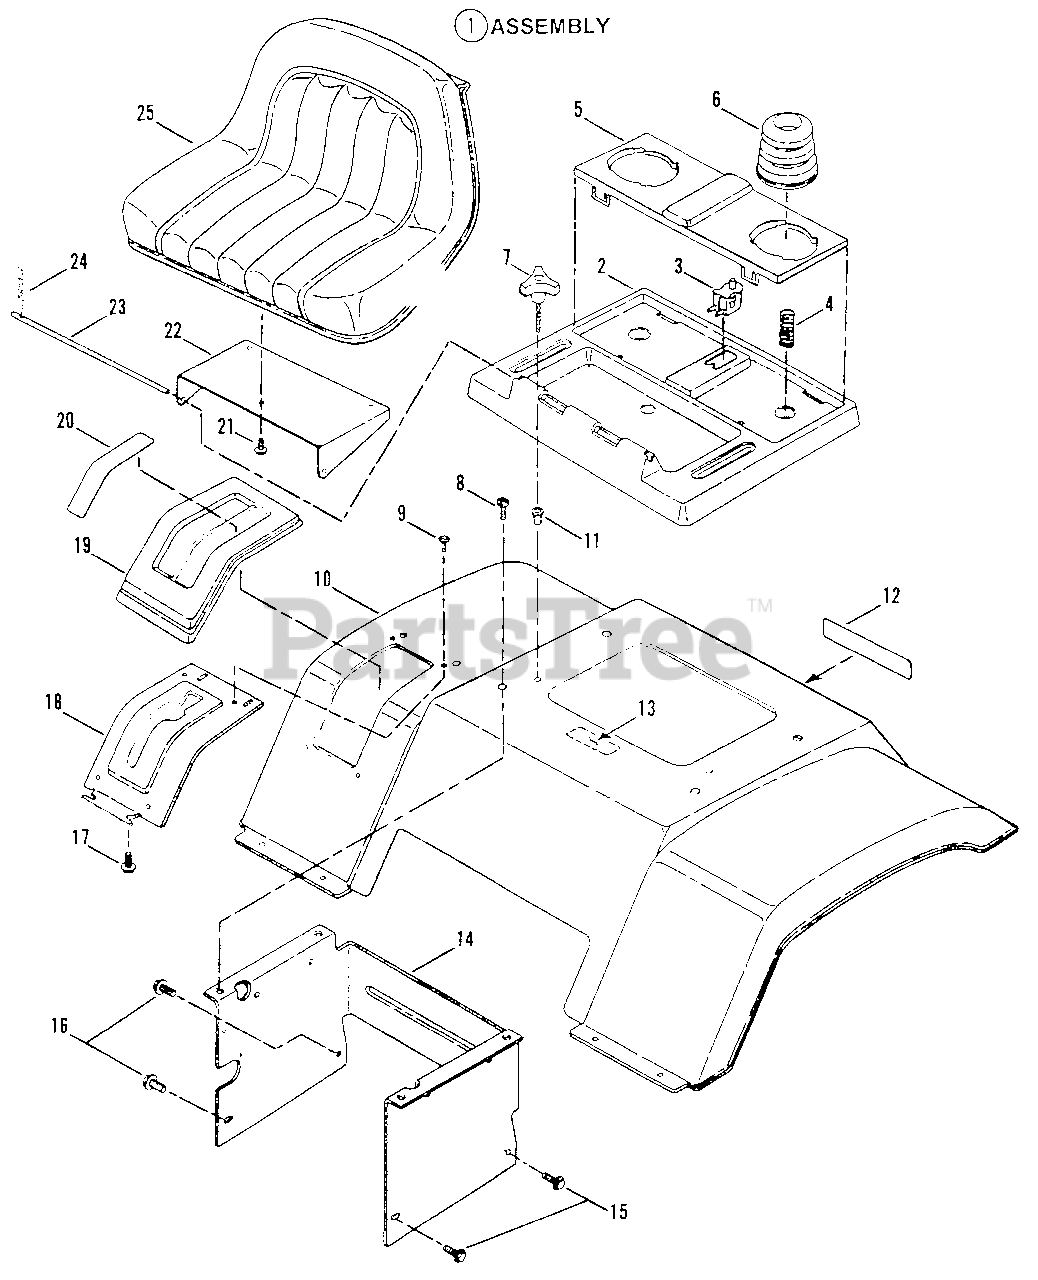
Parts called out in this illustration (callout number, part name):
1	ASSEMBLY, Seat Support
2	SUPPORT, Seat
3	SWITCH, Seat
4	SPRING
5	HOLDER, Cushion
6	CUSHION, Seat
7	KNOB, Seat Adjustment
8	SCREW, 5/16-18 x 5/8" Truss Head, Torx
9	SCREW, 1/4-20 x 5/8" Hex Washer Head, Self-Tapping
10	PAN, Seat (Fender)
11	RIV-NUT, 5/16-18
12	DECAL - BLACKHAWK, Molded Logo
13	DECAL - CAUTION, Battery Location
14	SUPPORT, Fender
15	SCREW, 5/16/18 x 5/8" Hex Washer Head, Swage Form
16	SCREW, 5/16-18 x 1 1/4" Hex Washer Head, Swage Form
17	SCREW, #10-16 x 1/2" Hex Washer Head, Self-Tapping
18	DETENT, Shift
19	COVER, Shift
20	DECAL, Shift Cover, 5-Speed (Hydro Drive)
21	BOLT, 5/16-18 x 1/2" Hex Flange Lock
22	BRACKET, Seat Support
23	ROD, Seat Hinge
24	PIN, 3/32 x 1 1/2" Hair
25	SEAT, Operator's
